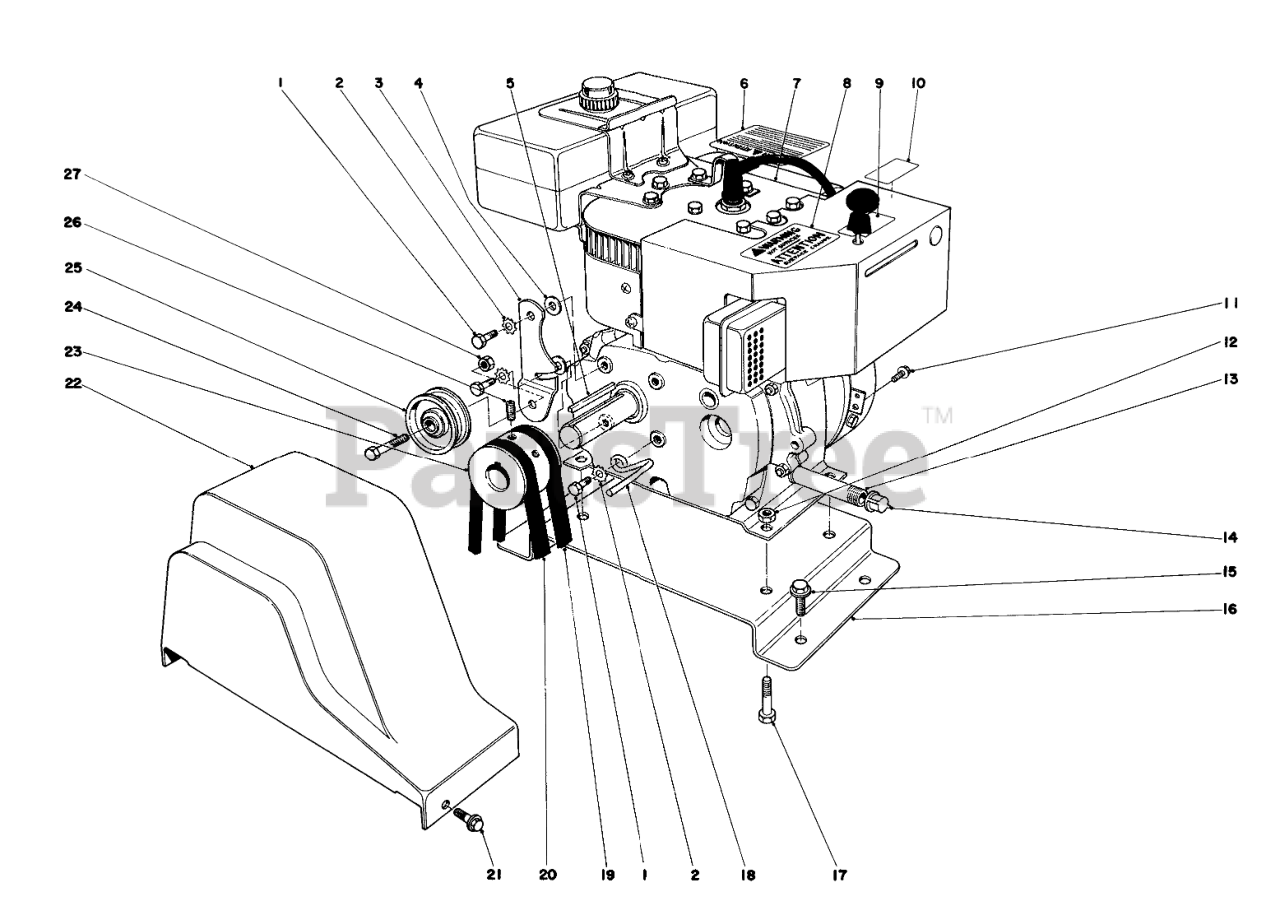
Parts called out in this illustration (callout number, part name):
1	SCREW-HH
2	WASHER-LOCK
3	ENGINE IDLER ARM
4	WASHER-PLAIN
6	CAUTION DECAL
7	Engine
8	Decal Hot Surface Warning
9	CHOKE DECAL
10	PRIMER DECAL
11	SCREW
12	NUT-LOCK, NI
13	NIPPLE-PIPE
14	CAP-PIPE
15	SCREW-HHFTF
16	ENG MTG PLATE R
17	SCREW-HH
18	BELT RETAINER
19	V-BELT
20	V-BELT
21	SCREW-HWH
22	BELT GUARD
23	ENGINE PULLEY
24	SCREW-HH
25	PULLEY-IDLER
26	Screw-Set
27	NUT-HEX
